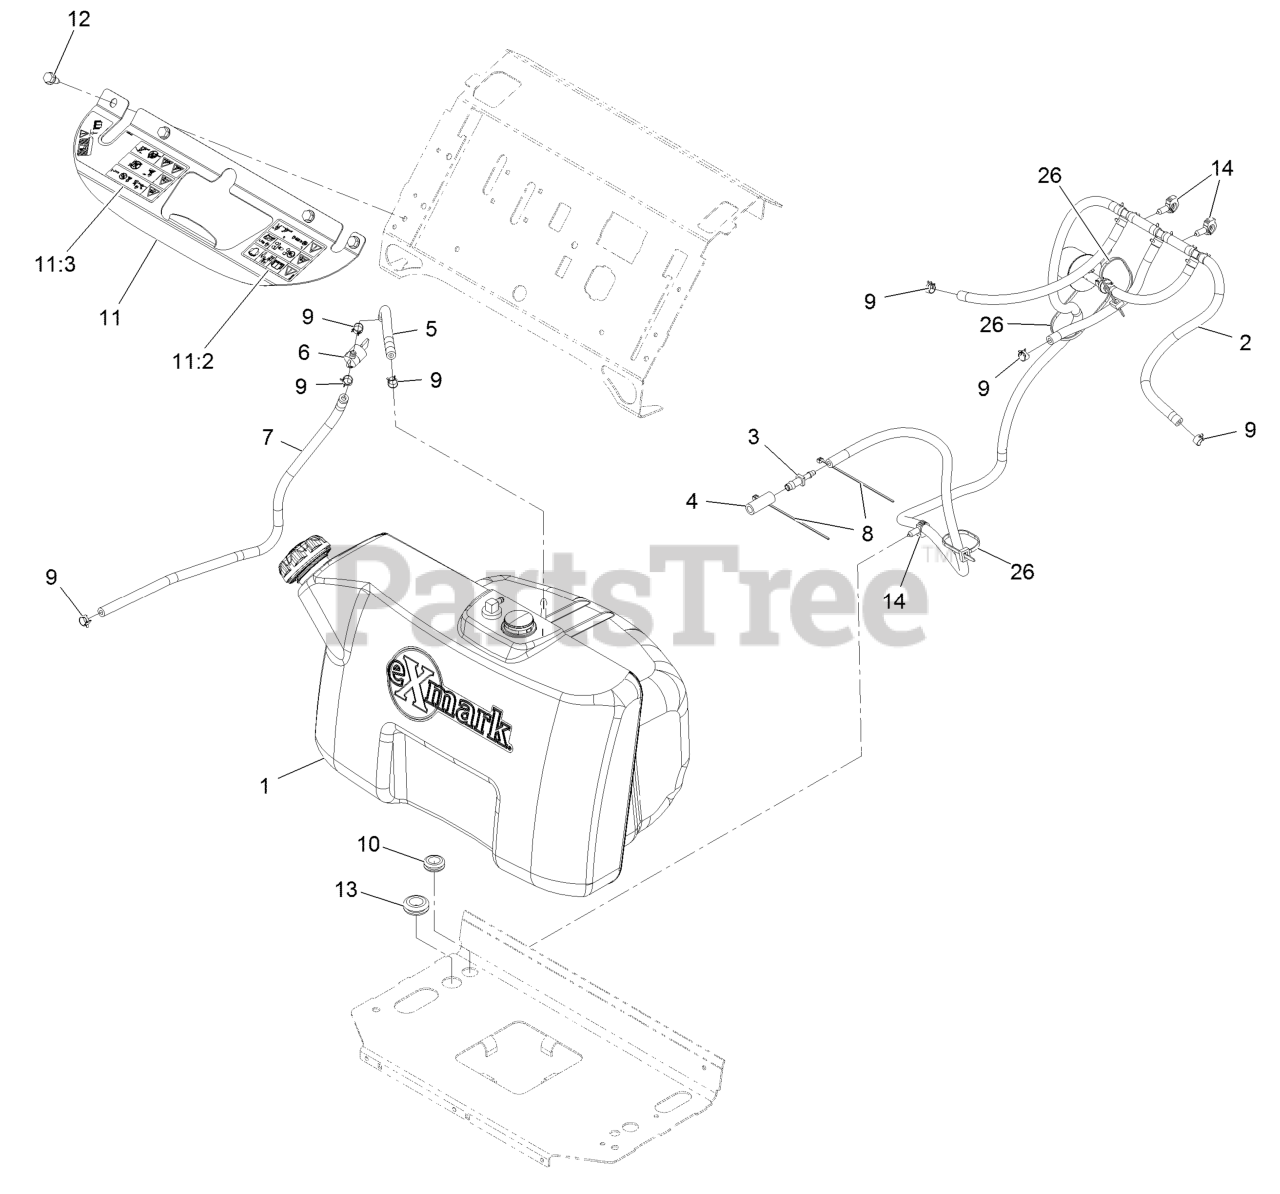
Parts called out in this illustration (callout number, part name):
1	TANK ASM-
2	VENT ASM
3	FITTING-STRAIGHT
4	HOSE-FUEL
5	HOSE-FUEL
6	VALVE-FUEL
7	HOSE-FUEL
8	TIE-CABLE
9	CLAMP-HOSE
10	GROMMET
11	BRACKET-TANK
11:2	DECAL-WARNING LH
11:3	DECAL-WARNING RH
12	Screw-HWH 5/16-18 X 3/4 Tf
13	GROMMET
14	CLIP-HARNESS
26	TIE-CABLE
